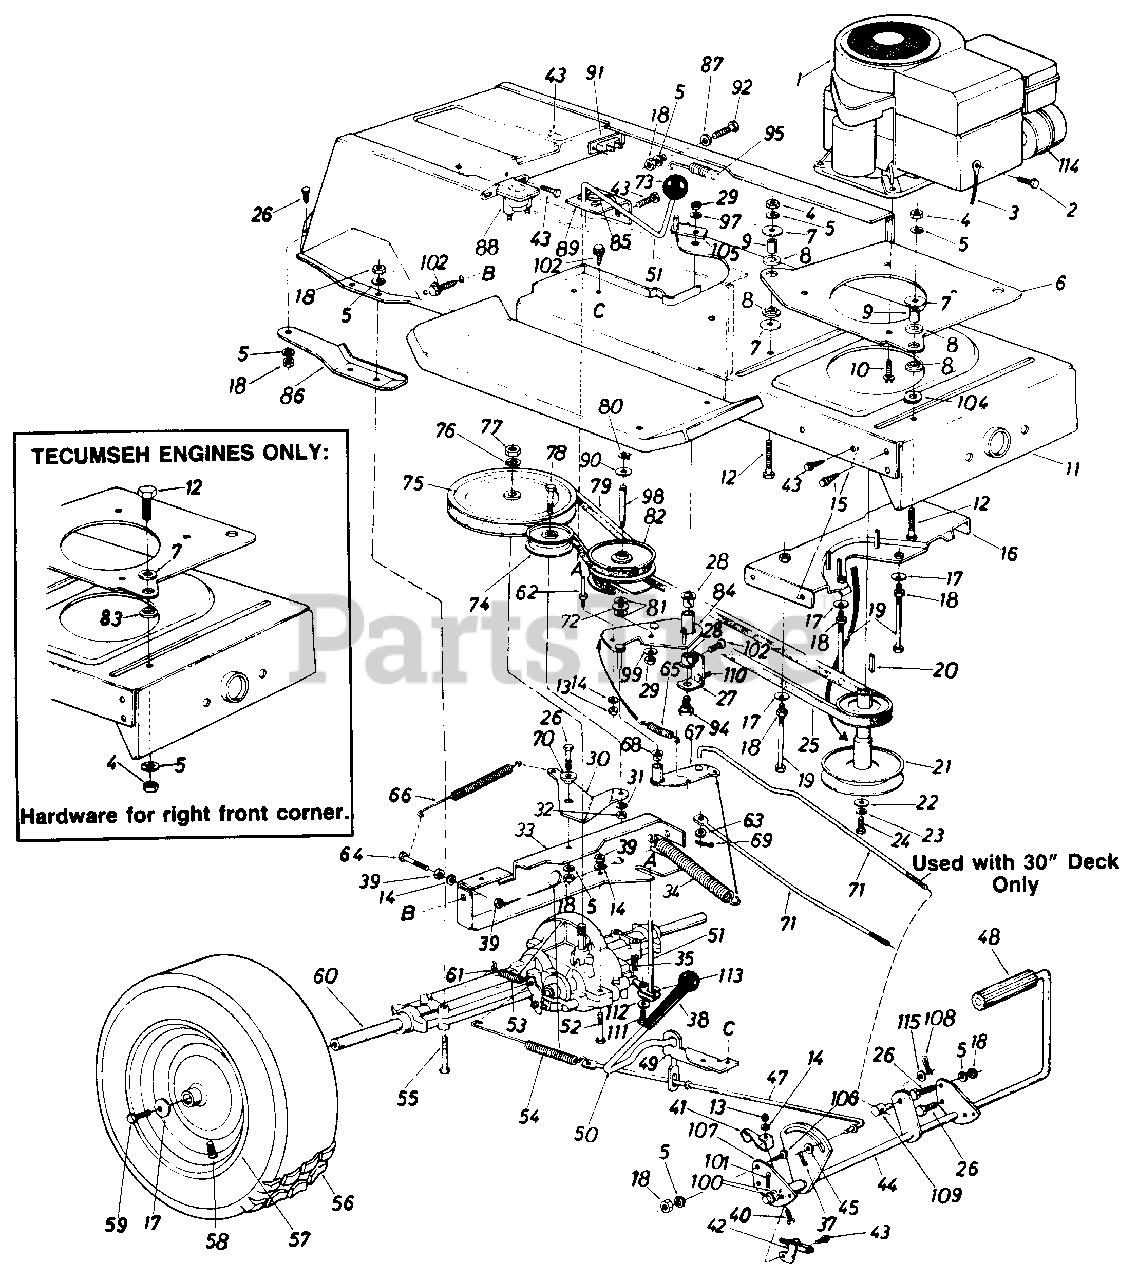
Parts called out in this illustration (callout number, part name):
1	Engine
2	Hex Bolt 1/4-20 x .62" Lg.
3	Electric Ground Wire
4	Hex Nut 5/16-24 Thd.
5	L-Wash. 5/16" I.D.
6	Engine Mounting Plate
7	Fl-Wash. .320" I.D. x 1.25"
8	Engine Mounting Grommet
9	Spacer
10	Hex Bolt 3/8-16 x 1.25" Lg.
11	Lower Frame Ass'y.
12	Hex Bolt 5/16-24 x 1.25"
13	Hex Nut 1/4-20 Thd.
14	L-Wash. 1/4" I.D.
15	Hex Wash. Hd. AB-Tap Scr. 5/16" x .75" Lg.
16	Belt Guard Brkt. Ass'y.
17	Bell-Wash. .345" I.D. x .88"
18	Hex Nut 5/16-18 Thd.
19	Hex Bolt 5/16-18 x 5.25" Lg.
20	Sq. Key 1/4" x 1/4" x 2.00"
21	Engine Pulley-30" R.D.
22	Fl-Wash. 7/16" I.D. x 1.25"
23	L-Wash. 7/16" I.D.
24	Hex Bolt 7/16-20 x 1.50" Lg.
25	Variable-Speed Belt
26	Hex Bolt 5/16-18 x .75" Lg.
27	Bearing Shaft Bracket Ass'y.
28	Flanged Nyliner Brg. 518" I.D. x .88" Lg.
29	Hex Nut 3/8-24 Thd.
30	Idler Bracket
31	L-Wash. 3/8" I.D.
32	Hex Nut 3/8-24 Thd.
33	Transaxle Support Brkt.
34	Ext. Spring .94" O.D. x 6.7
35	Inter. Cott-Pin
37	Cotter Pin 3/32" Dia. x .75"
38	Grip-Black
39	Hex Nut 1/4-28 Thd.
40	Hex Bolt 1/4-20 x 1.00" Lg.
41	Switch Actuator
42	Safety Switch
43	Hex Wash. Hd. S-Tap Scr. 1/4-20 x .50" Lg.
44	Clutch/Brake Pedal Ass'y.
45	Fl-Wash.
47	Brake Rod 20.9 Lg.
48	Foot Pad
49	Brake Lever Bracket
50	Hill Holder Brake Handle
51	Shift Lever Ass'y.
52	Hex Bolt 1/4-28 x 1.75" Lg.
53	Ext. Spring .38" O.D. x 2.5"
54	Ext. Spring .59" O.D. x 7.08"
55	Hex Bolt 5/16-18 x 2.75
57	Wheel Rim Only
58	Air Valve
59	Hex Bolt 5/16-24 x .75' Lg.
60	Transaxle Complete
61	Brake Return Spring Anchor
62	Belt Guard Pin 1/4-20 Thd.
63	Fl-Wash. .34" I.D. x .68" O.D
64	Hex Bolt 1/4-28 x 1.25" Lg.
65	Ext. Spring
66	Ext. Spring .62" O.D. x 6.12"
67	Variable Speed Torque Brkt. Ass'y.
68	Flanged Bearing
69	Cotter Pin 3/32" Dia.
70	Shoulder Spacer .27 Lg.
71	Speed Control Link
72	Truss Bearing .56 Dia. x 1 .25"
73	Ball Knob
74	Fl-Idler Pulley 3.25' x .75"
75	1/2" "V"-Pulley 8.0 O.D. x.501" I.D.
76	L-Wash. 1/2n I.D.
77	Hex Jam Nut 1/2-20 Thd.
78	Hex Bolt 3/8-24 x 1.75" Lg.
79	Variable Speed Belt
80	Snap Ring .56 Dia.
81	Fl-Wash.
82	Variable Speed Pulley Ass'y. 5" O.D.
83	Flange Wash.
84	Variable Speed Brkt. Ass'y.
85	Comp. Spring-Clip
86	Transaxle Support Brkt.-R.H.
87	Fl-Wash. .34 I.D. x 1.12 O.D.
88	Solenoid
89	Shift Lever Bracket
90	Teflon Washer 565" I.D.
91	Circuit Breaker
92	Hex Bolt 5/16-18 x 1.50"Lg.
94	Shld. Bolt 3/8-24 x 3.12" Lg.
95	Ext. Spring .99" O.D. x 11"
97	Bell-Wash. 38" I.D. x .88"
98	Shaft .56" Dia. x 3.875" Lg.
99	Bell-Wash. .39" I.D. x 1.12"
100	Fl-Wash.
101	Cotter Pin 3/32" Dia. x 1.0"
102	Hex Wash. Hd. Scr. 5/16-18 x.62" Lg.
104	Fl-Wash. .32" I.D. x 1.25"
105	Belt Guard
106	Truss Mach. Scr. 5/16-18 x .75" Lg.
107	Pedal Bracket
108	Cotter Pin 3/32" Dia. x 75
109	Ferrule
110	Hex Bolt 5/16-18 x 1.0" Lg. (Grade 5)
111	Hex Bolt 1/4-28 x 50 Lg.
112	Bell-Wash. .265" I.D. x .75"
113	Shift Lever Link Ass'y.
114	Muffler
115	Fl-Wash. .385" I.D. x .62
